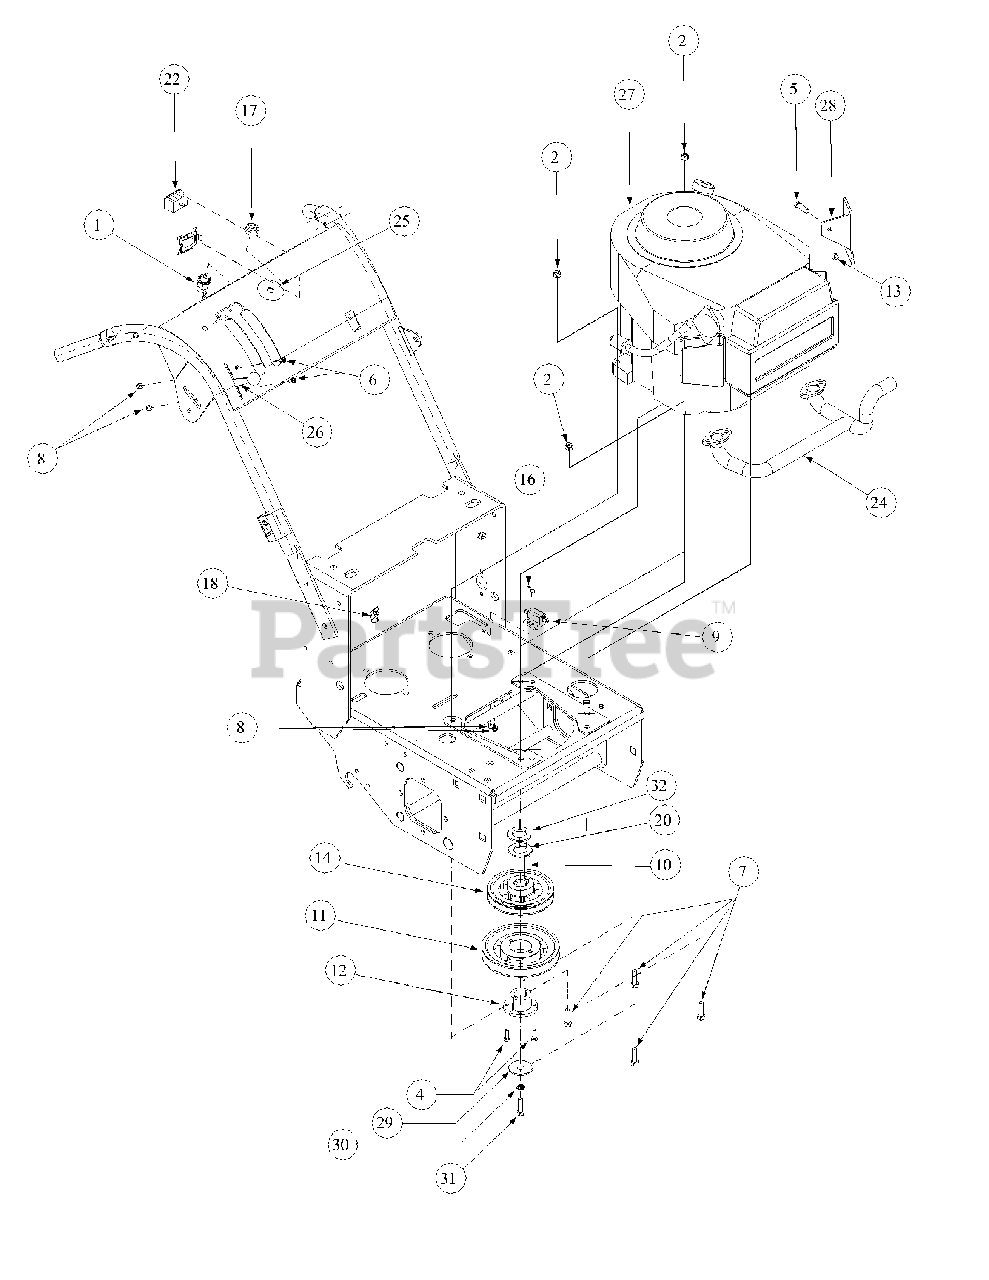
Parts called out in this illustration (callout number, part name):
1	On/Off Ignition Switch
2	Nylock Nut, 5/16-18
4	Hex Cap Screw, 1/4-20, .75
5	Hex Cap Screw, 5/16-18 x 3/4
6	Slotted Hex Washer Screw, 10-32 x 1/2
7	Hex Cap Screw, 5/16-18 x 2
8	Lock Nut, Nylon Insert, #10-32
9	Delta Switch, #5100-51
10	Key Stock, 1/4 x 1/4 x 2
11	Deck Pulley
13	Hex Nut, Center Lock, 5/16-18
14	Sheave 1" Bore w/2 Set Screws
15	Belt, Hydro Pump
16	Phil. He. Mach. Screw #10-32 x 5/8
17	Nut w/Cap, 5/8-32 Ignition
18	Support Clamp, 3/8 OD
19	Harness Wire
20	Flat Washer
22	Hour Meter
23	Harness Hourmeter
24	Kawasaki Manifold
25	Decal, Pull Start Overlay
26	Throttle Control w/Detent, 57.2
27	Kawasaki Engine, 15HP
28	Muffler Kawasaki Bracket
29	Clutch Washer
30	Lock Washer, 7/16
31	Capscrew, 7/16-20 x 1-1/4
32	Spacer Pulley Engine
